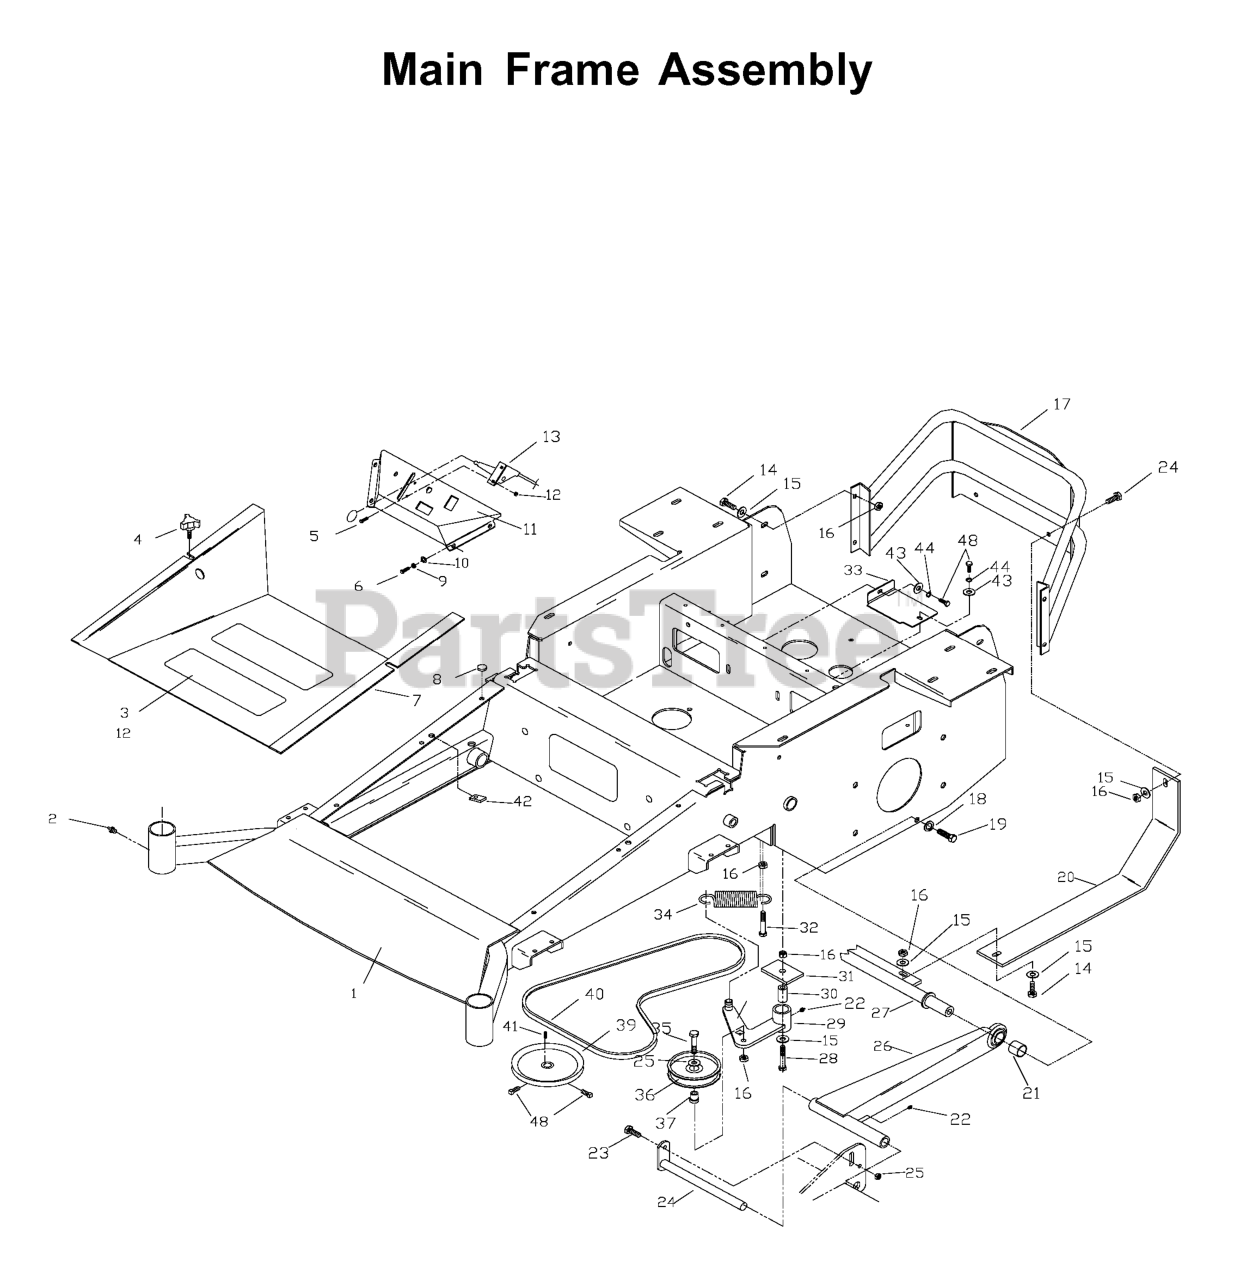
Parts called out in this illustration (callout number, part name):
1	MAIN FRAME W/DECALS
3	ANTI-SKID PAD
4	KNOB W/STUD
5	HCS #10-24 X 1/2
6	SCREW 1/4 X 5/8
7	FOOT PLATE WIDMT
8	GROMMET, BUMPER
9	LOCKWASHER 1/4"
10	WASHER 1/4 FLAT
11	CONSOLE W/DECALS
12	NUT 10-24 NYLOC
13	THROTTLE CONTROL W/BALL KNOB
14	HCS 3/8-16X1.GRD.5.ZD
15	WASHER 3/8 FLAT
16	NUT 3/8C CENTERBLOCK
17	REAR GUARD
18	WASHER 7/16 LOCK
19	HEX SCREW 7/16-14 X 1 GR8
20	SKID PLATE
21	SPACER, STRUT
22	ZERK
23	HCS 5/16C X 3/4
25	NUT 5/16C CENTERLOCK
27	CROSS SHAFT WLD 72
28	HCS 1/2C X 3 1/4
29	IDLER ARM WLDT
30	PIVOT BUSHING
32	HCS 3/8C X 1 1/2
33	IDLER COVER
35	HCS 3/8-16 X 1 3/4 GR5
36	IDLER PULLEY
37	BUSHING, IDLER FLANGE
38	SCREW 5/16C X 5/8 SQ HEAD
40	PUMP BELT
41	KEY 5 MM SQ X 25 MM
42	U-CLIP 5/16-18 NUT RETAINER
43	WASHER 5/16 FLAT
44	WASHER.LOCK.HVY.HLCL.SPR.5/16
45	STRUT WELDMENT
46	STRUT PIN RH
47	STRUT SPACER - 72"
48	HCS 5/16C X 1
539104332	CROSS SHAFT WLDMT
539105886	FRAME 52" & 61"
